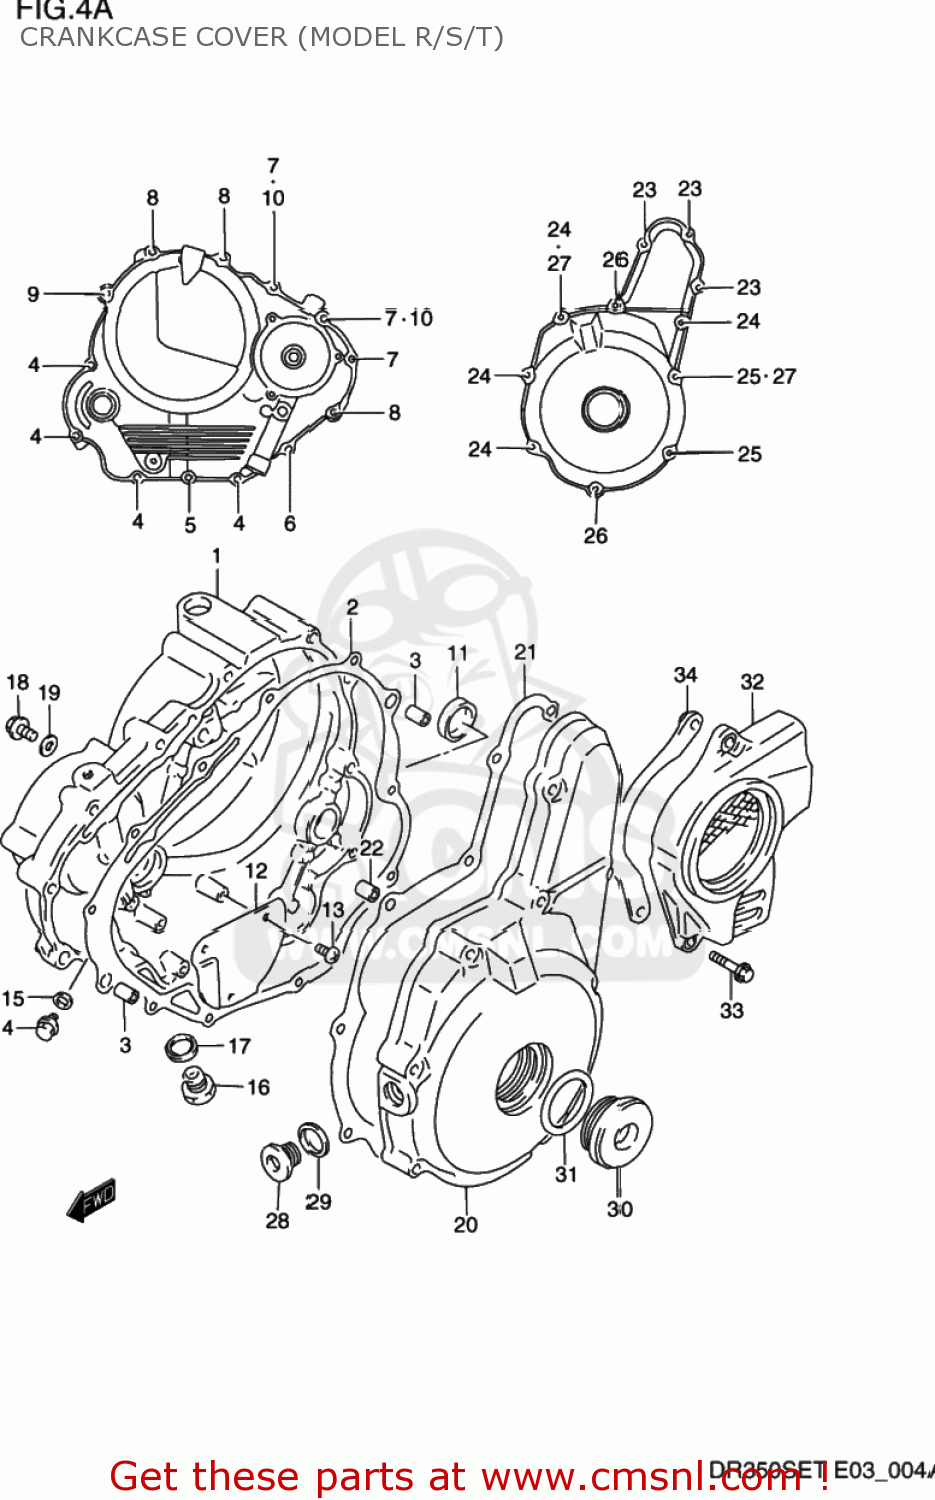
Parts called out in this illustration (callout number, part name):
1	COVER,CLUTCH
2	GASKET,CLUTCH COVER (NAS)
3	PIN
4	SCREW
5	BOLT,G/S SWITC
6	BOLT
7	BOLT
8	BOLT
9	BOLT
10	GASKET(5.8X11X1.2) (NAS)
11	PLUG,CLUTCH COVER KICK
12	SEPARATOR,OIL RETURN
13	SCREW
14	BOLT(6X8)
15	GASKET(6.2X11X1).2 (NAS)
16	PLUG(10X6.8)
17	GASKET(10X14X3.6) (NAS)
18	SCREW (6X10)
19	GASKET(5.8X11X1.2) (NAS)
20	COVER,MAGNETO
21	GASKET,MAGNETO COVER (NAS)
22	PIN
23	SCREW
24	BOLT
25	BOLT
26	BOLT
27	GASKET(5.8X11X1.2) (NAS)
28	PLUG,14X12
29	GASKET(13.8X18.8X4.8) (NAS)
30	PLUG(SILVER)
31	O RING(D:3.1,ID:32.7)
32	COVER,ENGINE SPROCKET
33	SCREW
34	PLATE,FR CHAIN GUIDE
